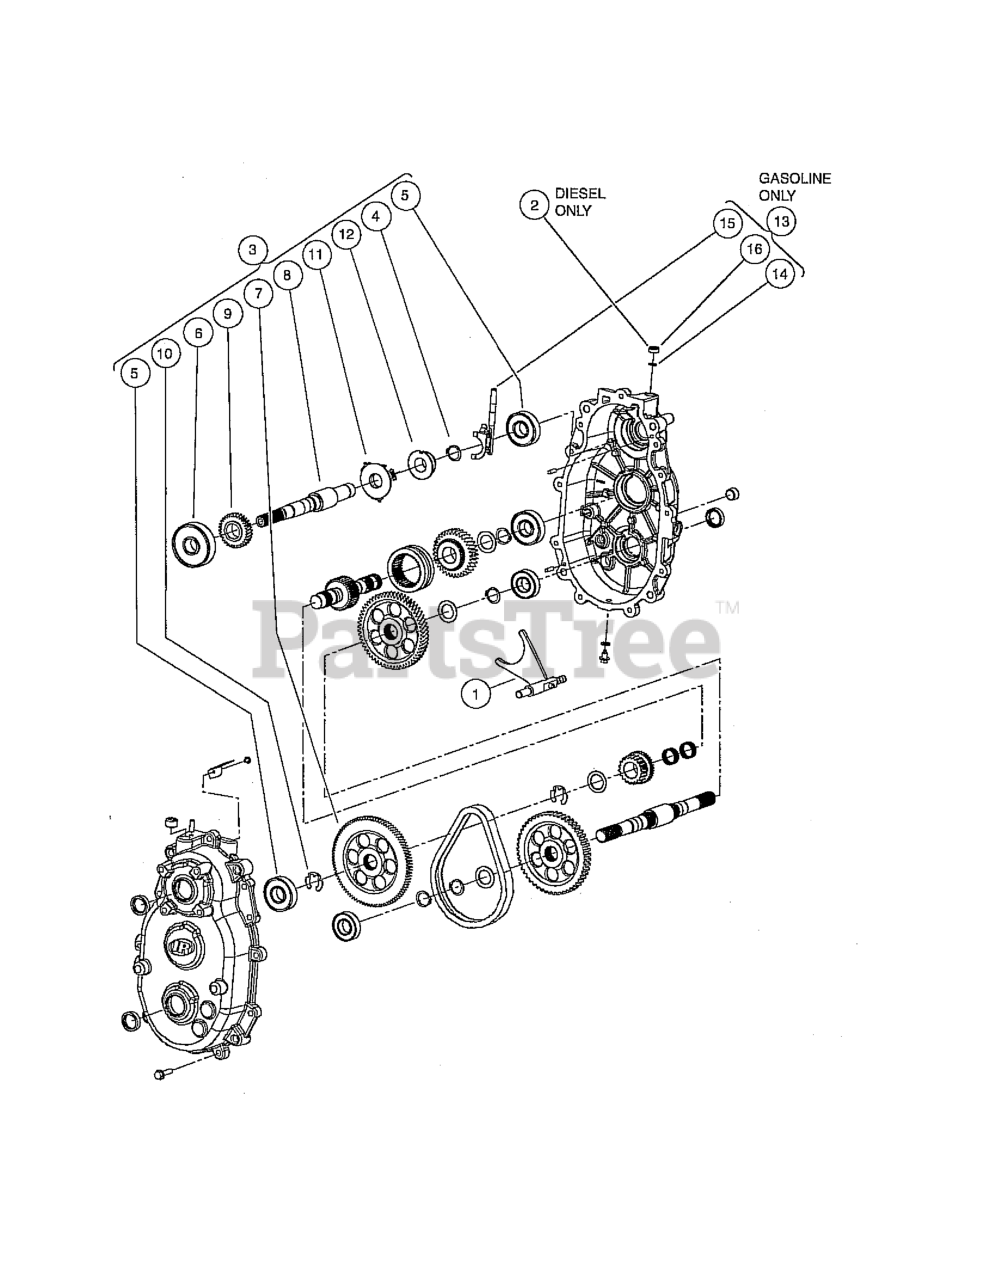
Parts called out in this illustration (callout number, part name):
1	FORK, WA, TRANS
2	PLUG, 19MM
3	KIT-INPUT SHAFT REPAIR
4	RING, RETAINING, BASIC EXTERNA
5	BEARING, BALL, 6305 C3
6	BEARING, BALL, 6405 C3
10	RING, RETAINING, E-RING, PO-10
13	KIT-GOVERNOR SHAFT REPAIR
15	ASSY, GOVERNOR ARM
16	SEAL, DUAL LIP
